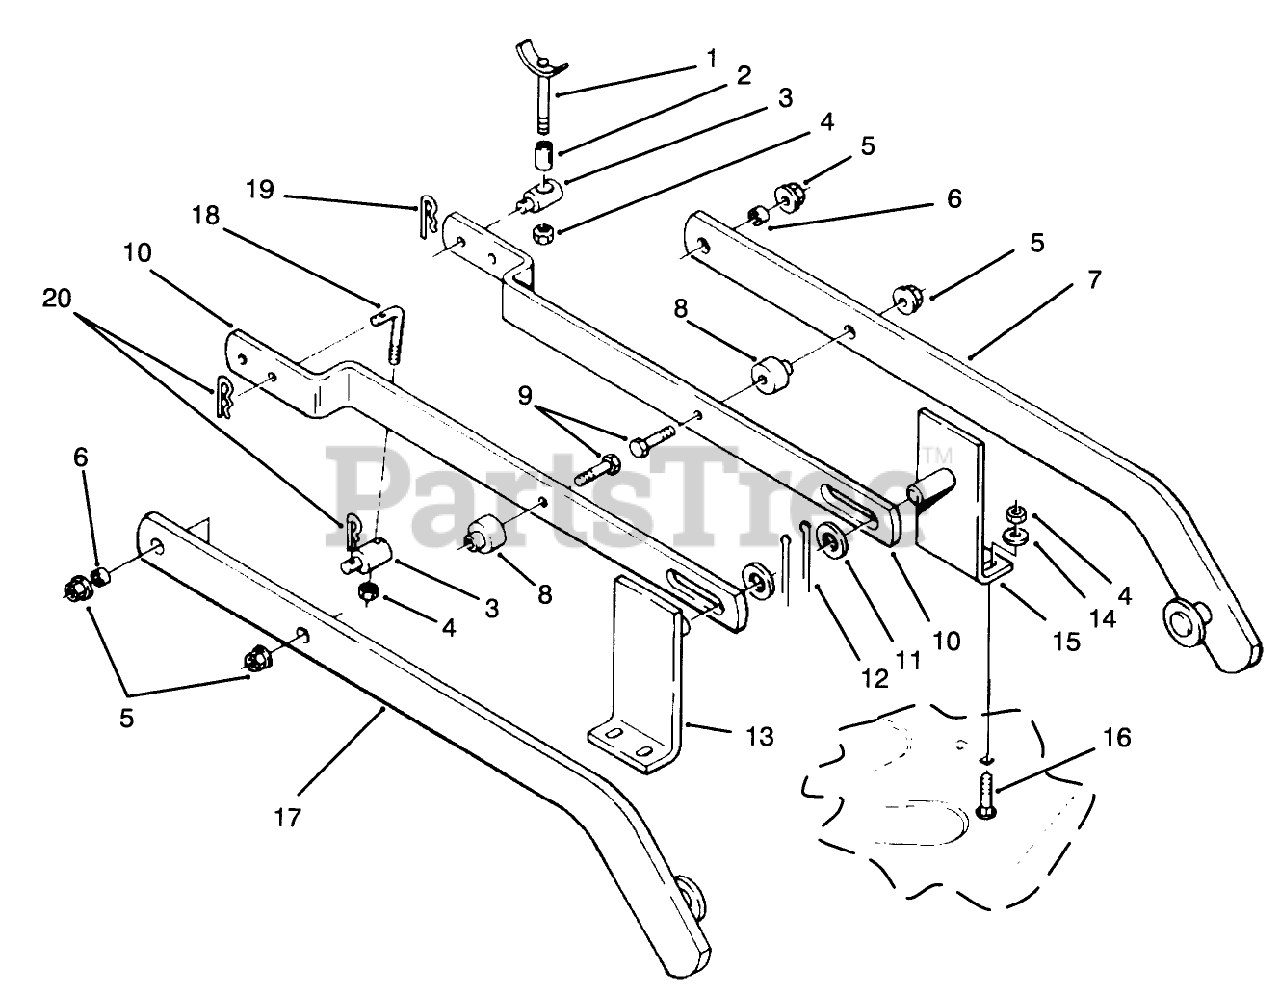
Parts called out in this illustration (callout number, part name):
1	WLDMT-HANGER ROD
2	SPACER .375 ID X 1.6
3	TRUNNION
4	NUT-LOCK, NI
5	LOCKNUT-FLANGE
6	SPACER
7	Draft Bar LH
8	SPACER
9	SCREW-HH
10	Bar-Leveler
11	WASHER-FLAT
12	PIN-COTTER
13	Bracket RH
14	WASHER-FLAT
15	Bracket
16	BOLT-CARR
17	Draft Bar RH
18	ROD-LIFT
19	PIN-HAIR
20	PIN-COTTER
